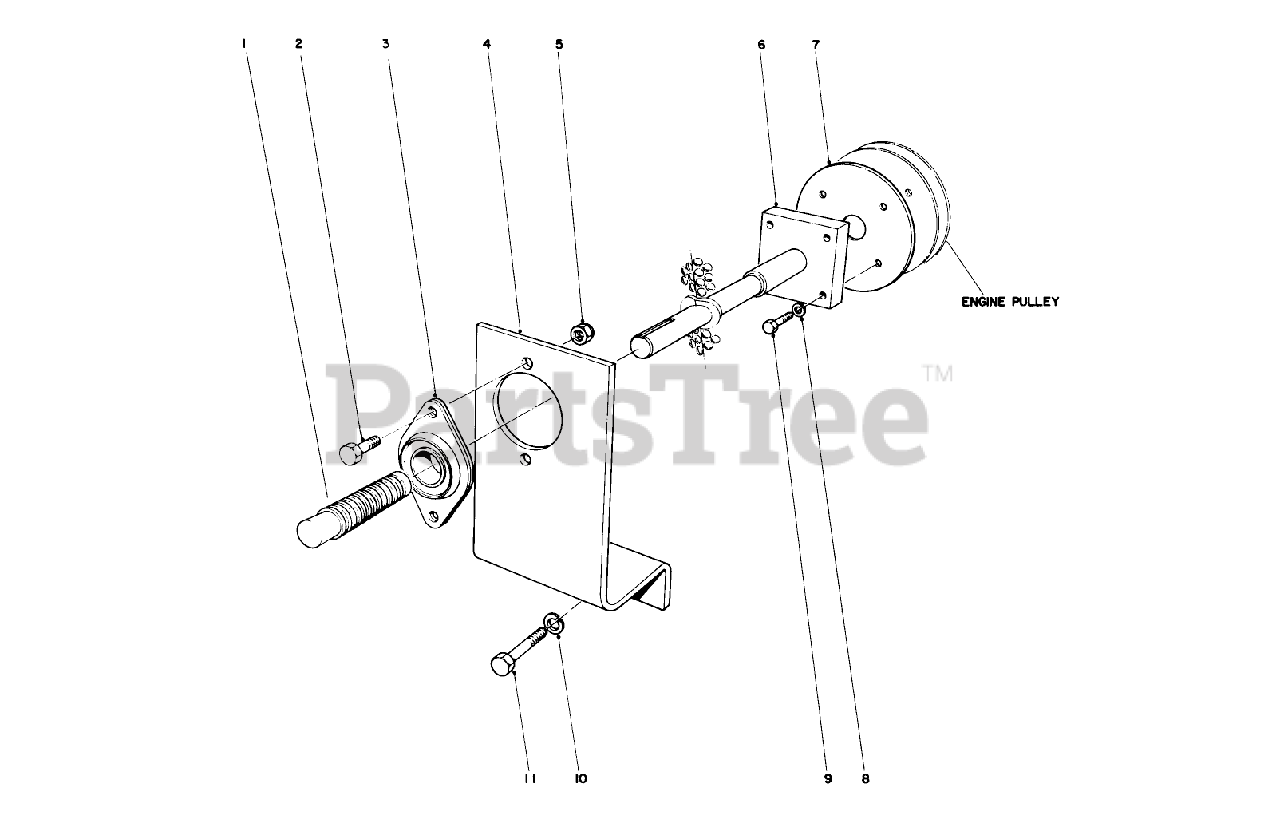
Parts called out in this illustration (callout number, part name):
1	Handle Grip
2	SCREW-HH
3	Bearing
4	PTO Brng. Mtng. Brkt.
5	NUT-LOCK, CONE
6	PTO Shaft W.A.
7	Grommet
8	WASHER-LOCK
9	SCREW-HH
10	WASHER-LOCK
11	SCREW-HH
